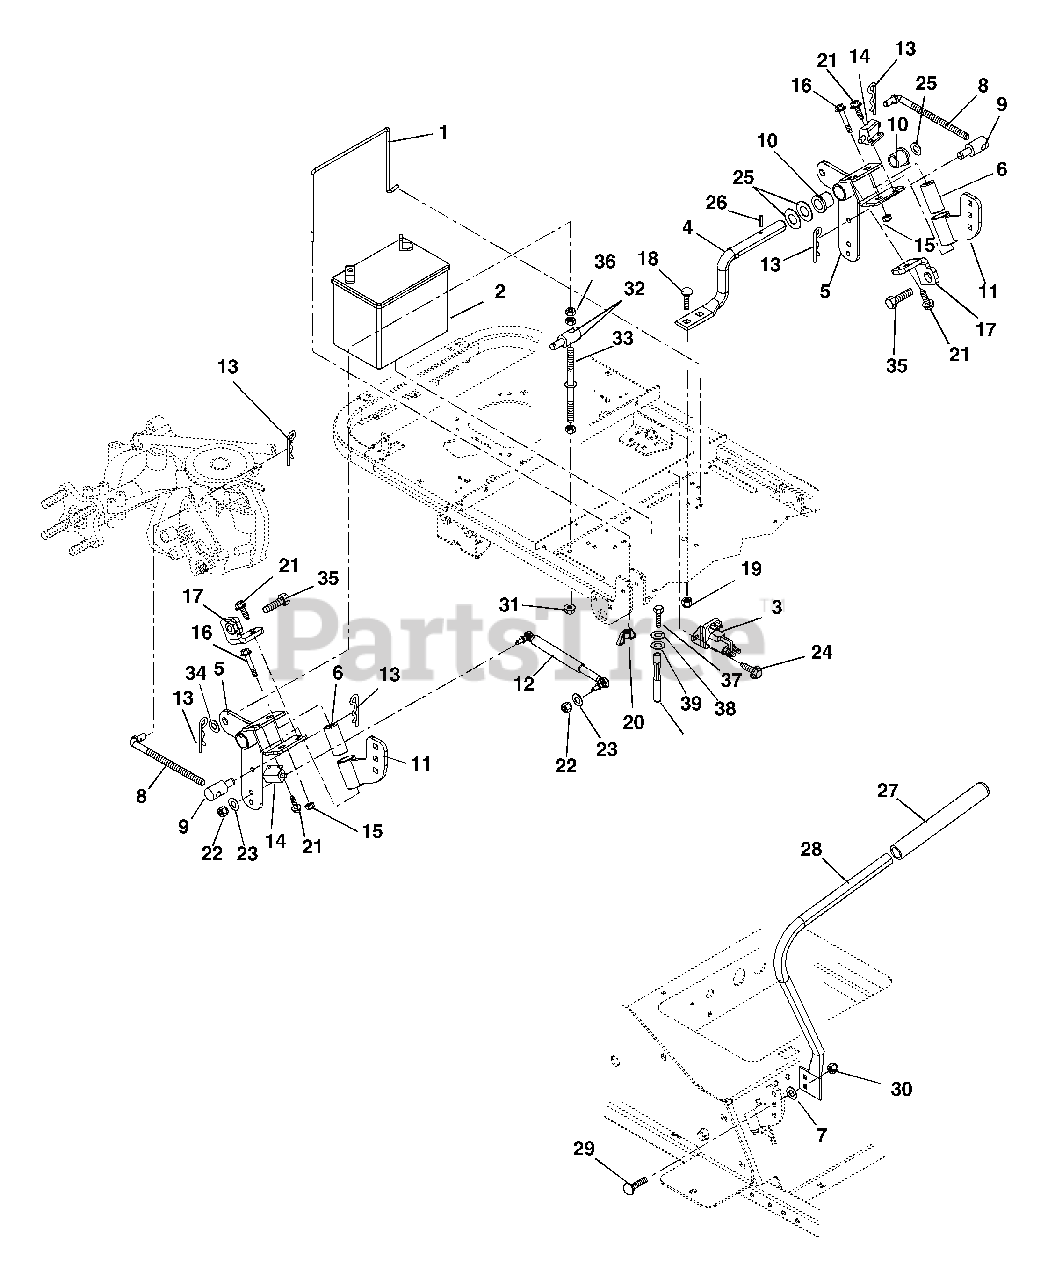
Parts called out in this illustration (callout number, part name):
1	BATTERY ROD
2	BATTERY, 300 CCA 10U1L
2	BATTERY W/ TUBE
3	SOLENOID
4	ROD PIVOT
5	WMT, CONTROL
6	BSHG, SPCR .502X.997X2.03 PM
7	@WSHR-LK-EXT.326X.599X.031YWZC
8	LINK,WIREFORM
9	PIVOT, ROD (TRUNNION ) .50
10	BUSHING-1"X.75"X1"
11	WMT, HANDLEBAR
13	PIN-HAIR, ENDRIES #25 YWZC
14	SWITCH- DOUBLE POLE N.O./N.O.
15	@NUT-LK-TOP-FLG .50-13 YWZC
16	@BLT-HEX .50-13X3.00 GR5 YWZC
17	WMT, HANDLE STOP
18	@BLT-RDHDSQNK .38-16X1.00 G5YZ
19	@NUT-LK-NYL-FLG .38-16 YWZC
20	NUT-LK WING .250-20 YWZC
21	@SCR-TAP 10-24X.50 HWH TR YWZC
22	NUT-HEX M8-1.25 YWZC
23	@WSHR-LK .31X.078 REG YWZC
24	@SCR-TAP .25-20X.37 HWH YWZ TR
25	WSHR-FL-STL .754X1.000X.032 YZ
26	PIN-ROLL .188X1.13
28	HANDLEBAR WLDM'T RH
28	HANDLEBAR WLDM'T LH
29	BLT-RDHDSQNK.31-18X.88 GR5YWZC
30	@NUT-LK-NYL-FLG .31-18 YWZC
31	@NUT-LK-NYL-FLG .38-16 YWZC
32	@NUT-HEX .38-16 YWZC
33	TRACKING ROD
34	NUT-LK-JAM-PTCH 1.00-20
35	SCR-SKH .25-20X1.25 PL
36	TRUNNION
37	@BLT-HEX .31-18X1.00 GR5 YWZC
38	@WSHR-LK .31X.078 REG YWZC
39	@WSHR-FL-STL.344X.688X.065YWZC
